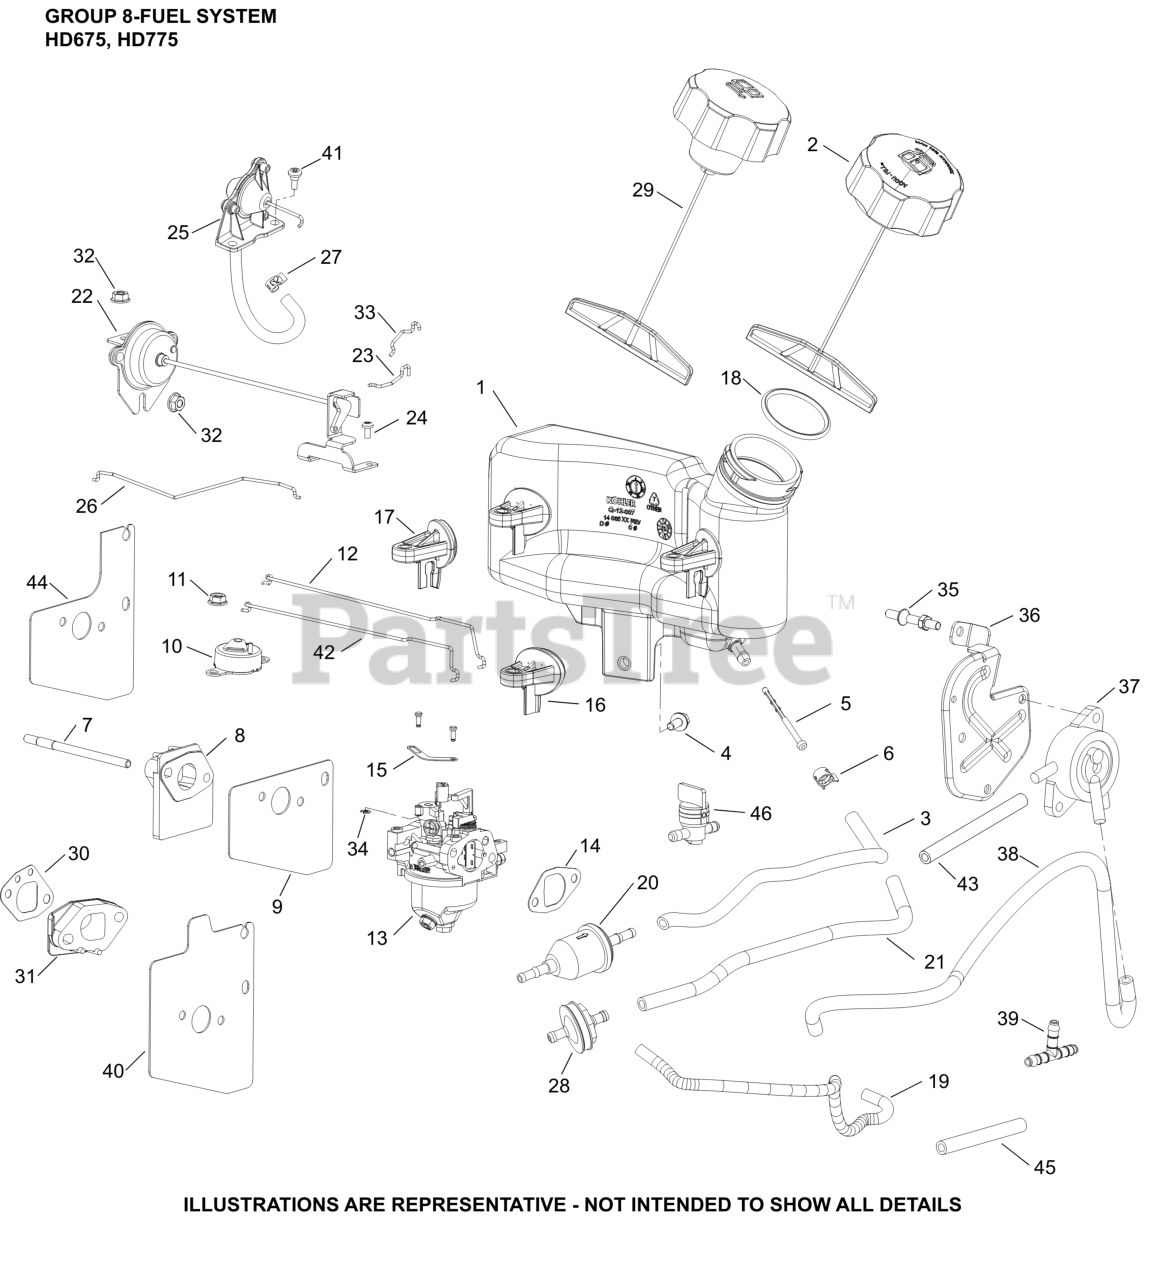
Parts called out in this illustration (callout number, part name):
1	FUEL TANK (50-STATE)
4	SCREW, THREAD FORMING-USE 25 086 472-S
5	FILTER, FUEL IN-NIPPLE
6	CLAMP, HOSE
7	STUD,M6X1.0X100.2MM
9	KIT, CARBURETOR HEAT SHIELD GASKET
13	KIT, CARBURETOR COMPLETE
13	KIT, CARBURETOR
14	KIT, INTAKE GASKET
15	LINKAGE, CHOKE
21	HOSE, FUEL LOW-PERMEATION (CKY)
22	ARM ASSEMBLY, AUTO CHOKE
24	SCREW, M4 THREAD FORMING
29	FUEL CAP (CARB)
30	GASKET, SPACER - USE 14 041 24-S
31	SPACER, CARBURETOR
32	NUT, HEX FLANGE (M6)
33	LINKAGE, AUTO CHOKE
36	BRACKET,FUEL PUMP MOUNT-USE 14 126 103-S
37	PUMP, FUEL
38	HOSE, VENT
39	FITTING, TEE
NI	KIT, HIGH ALT (4000-8000 FT)
NI	KIT, CARB REPAIR - USE 14 757 03-S
NI	KIT, CARBURETOR REPAIR (RUIXING)
